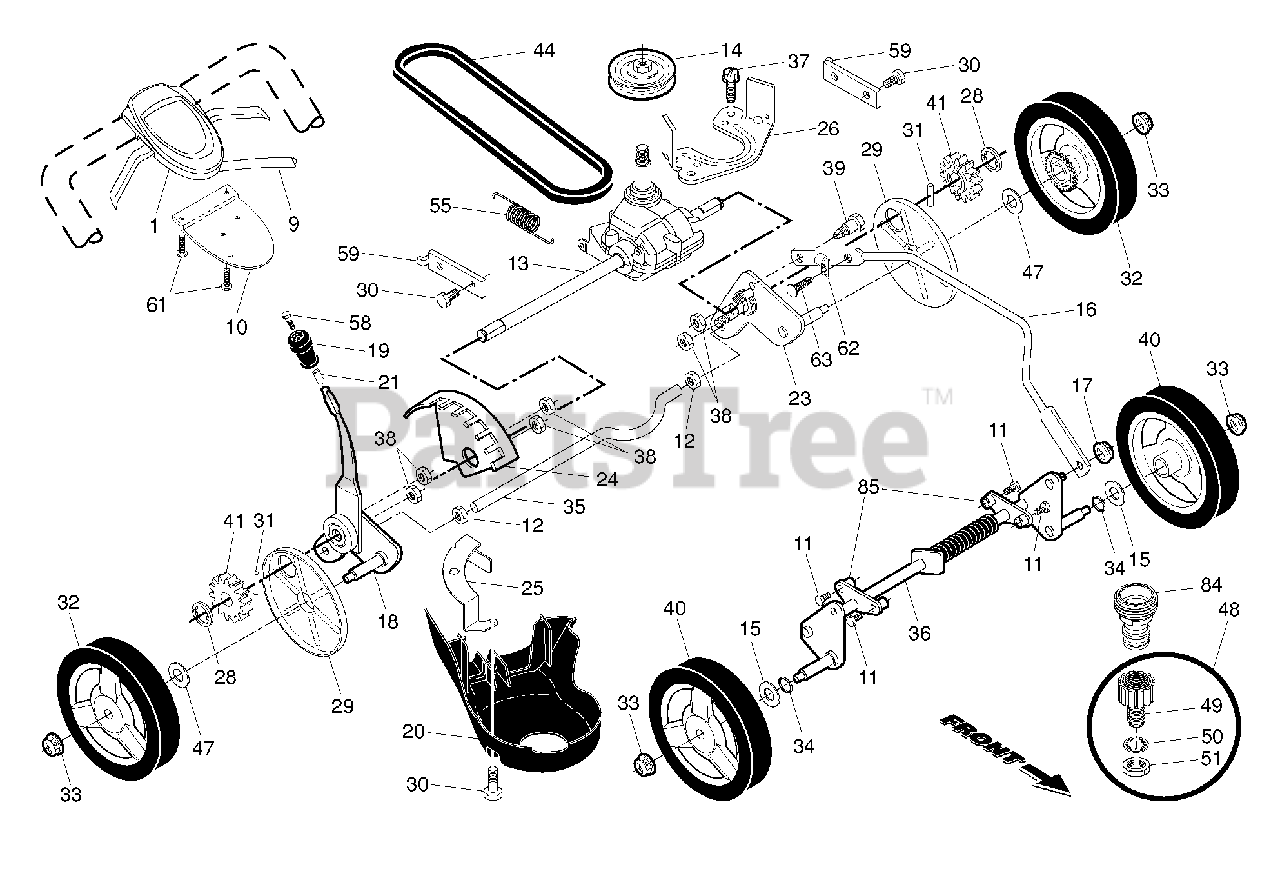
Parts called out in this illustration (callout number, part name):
1	RB CTRL.AW2.22+RGD.BS.GRY/BLK
9	CABLE.CONTROL.22RGD.GEN2
10	BRACKET.DRIVE.CONTR.GEN2.BLACK
11	SCREW.HX.13X.750
12	NUT.HEX.1/2-20
13	RP TRANSMISSION.22+.RGD.AW2/
14	PULLEY.1.PIECE
16	ROD.CONNECTING.RGD.22+.HW.BLAC
17	NUT.LOCK.5/16-18
18	KIT.SELECTOR.ASM.437869
19	KNOB.SEL.SPRING.22+.SP.RIB.BLK
20	RP.COVER.REAR.DRIVE.22+
21	SCREW.PLASTIC.ANCHOR.5/16
23	ADJUSTER.ARM.ASM.AX.RT.SP.ZC
24	BRACKET.WHL.ADJ.9.POS.W/PAD
25	BRACKET.DRIVE.COVER.RGD.BZP
26	BRACKET.TRANS.BELTKEEP.22+RGD
28	E-RING 7/16 RE
29	COVER.DUST.WHEEL
30	BOLT.5/16HEX.WHS.HD
31	PAWL, DRIVE
32	KIT.WHEEL.442789X460.8"
33	NUT.HEX.FLANGE.3/8-16.LO(3 2)
34	O-RING..070X.487.NEOPRENE
35	AXLE.REAR.RGD
36	AXLE.ASM.FRONT.RGD.CLEAR.ZINC
38	NUT.HEX.FLANGE.1/4
39	SHOULDER BOLT SEMI GIMLET PT.
40	WHEEL.8IN.H3SPK.ALPHA.
41	PINIION.14.TOOTH.RGD
44	BELT.DRIVE.RGD.BBC
47	WASHER FLUT
48	KIT.WASH-OUT.PORT.ZINC.WALK
49	WASHOUT.PORT.ZINC.RGD.22+
50	WASHER.LOCK.INTERNAL.TOOTH
51	LOCKNUT.HEX.WITH.O-RING
58	SCREW.12-14X1.500
59	BRACKET.SUPPORT.22+RWGD.BZP
61	SCREW, PHILLIPS HEAD 10 X 5/8
62	CLIP.CABLE.BLK
63	FASTENER.PUSH.O.250X0.783
84	COUPLING.QUICK CONNECT
85	BRACKET.FRT.AXLE.SUPPORT
